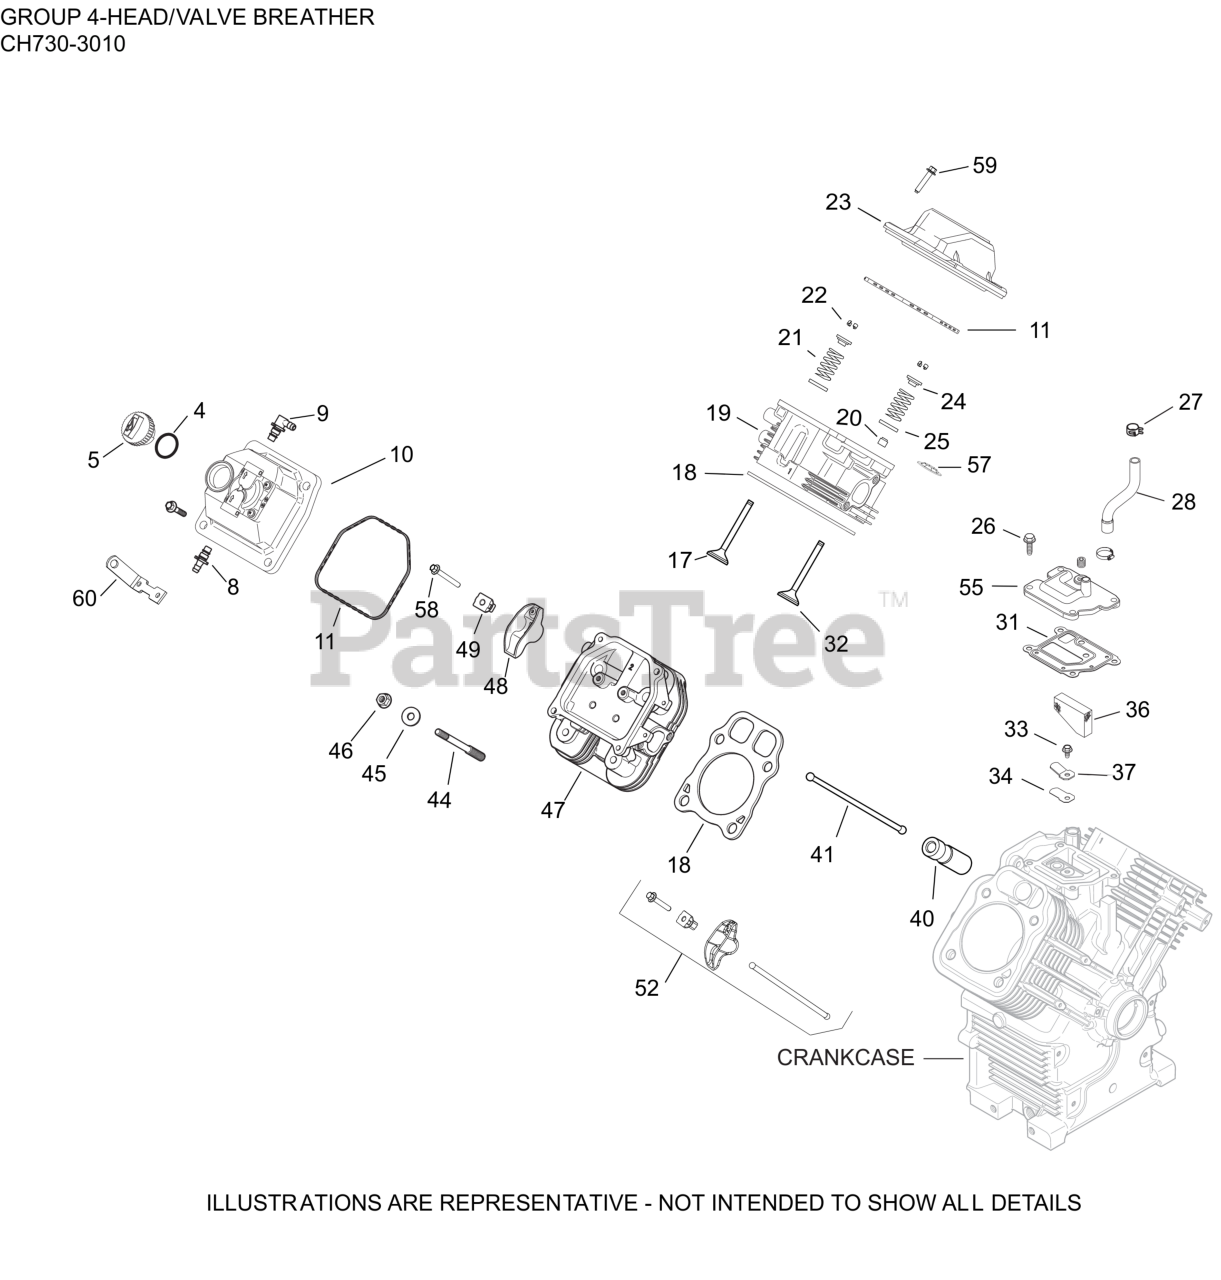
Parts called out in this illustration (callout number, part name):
5	CAP ASSY, OIL FILL (YELLOW)
8	KIT, STRAIGHT FITTING
9	KIT, 90 DEG. FITTING
10	KIT,VALVE COVER-FUEL PUMP
11	O-RING (YELLOW), VALVE CO
17	VALVE, EXHAUST
17	VALVE, EXHAUST (.25)
18	KIT, GASKET CYLINDER HEAD
19	KIT, CYLINDER HEAD (#1)-(#2481803S)
20	SEAL, VALVE BAND
21	SPRING, VALVE
22	KIT, RETAINER
23	KIT, VALVE COVER-PLAIN (PLASTIC)
24	CAP, VALVE SPRING
25	RETAINER, SPRING
26	SCREW, THREAD FORMING
27	SPRING CLAMP, HOSE
28	KIT, BREATHER HOSE AND CLAMP
31	GASKET, BREATHER
32	VALVE, INTAKE (STD)
32	VALVE, INTAKE (.25)-(#DSC)
33	SCREW, FLG THD FRM M5X.8X10
34	REED, BREATHER
36	FILTER, BREATHER
37	RETAINER, REED
40	LIFTER, VALVE HYDRAULIC-USE 25 351 11-S
41	ROD, PUSH
44	STUD, M8X1.25
45	WASHER, FLAT 8.6 MM
46	NUT, FLG M8X1.25
47	KIT, CYLINDER HEAD (#2)-(#2481804S)
48	ARM, ROCKER
49	PIVOT, ROCKER ARM
52	KIT, VALVE TRAIN
55	COVER, BREATHER
57	RETAINER, VALVE GUIDE (KM)
58	SCREW, HEX FLANGE
59	SCREW, HEX FLANGE (M6 X 31.625 DOG PT)
60	STRAP, LIFTING
